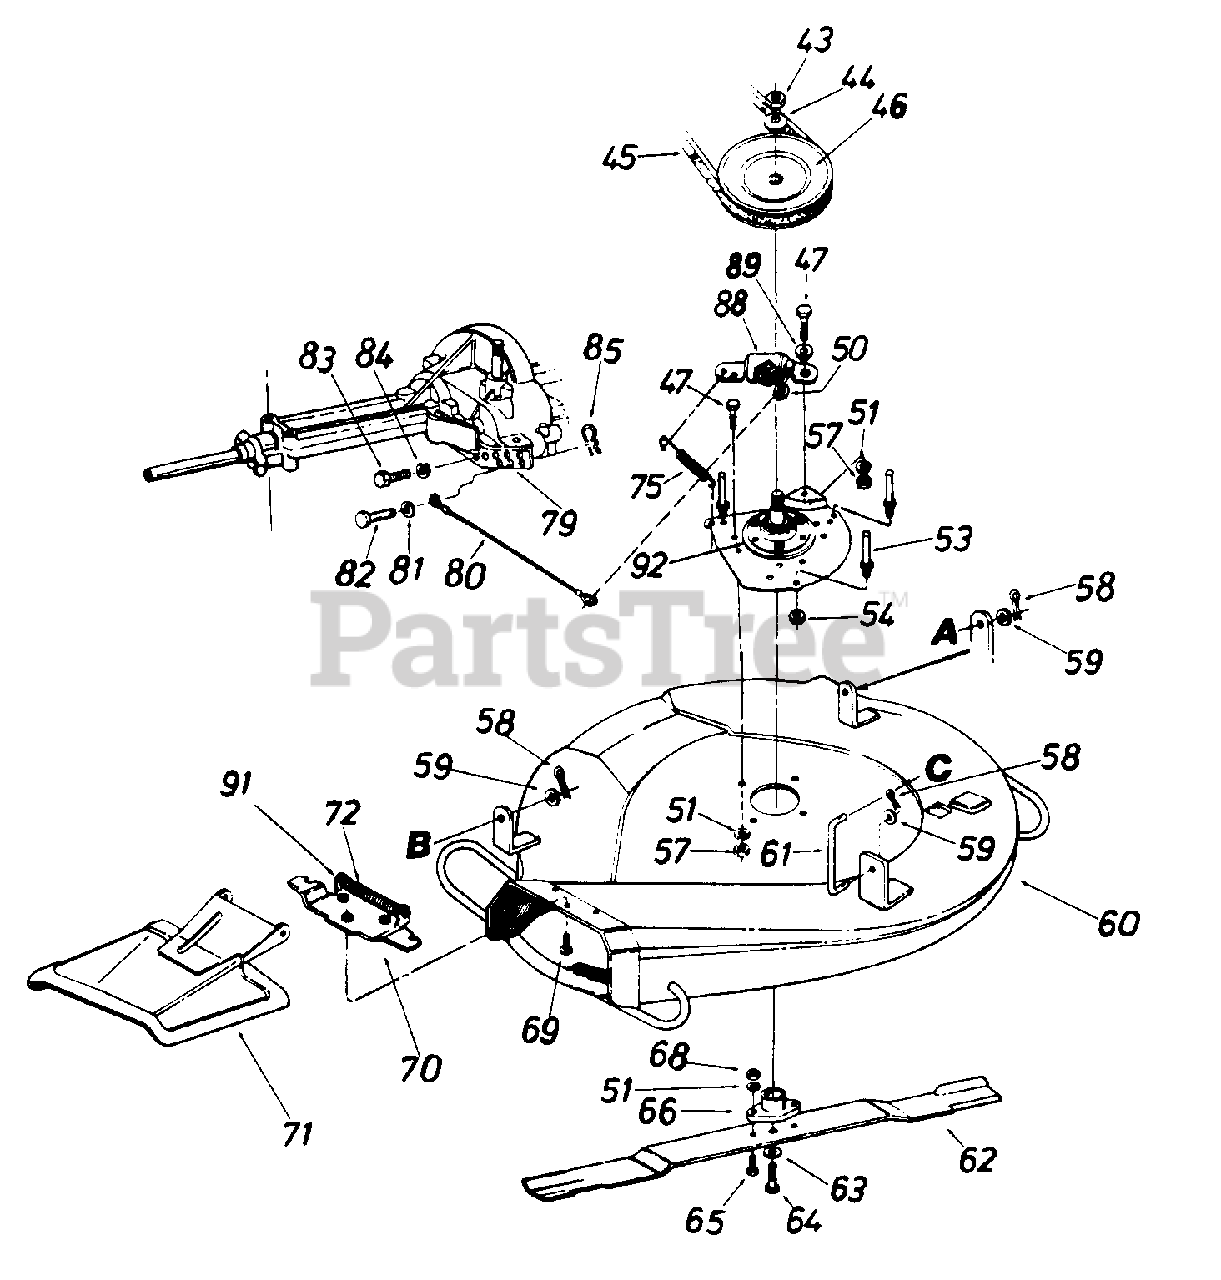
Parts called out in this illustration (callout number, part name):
43	Hex Jam Nut 5/8-18 Thd.
44	Bell-Wash. 63" I.D. x 1.25" O.D.
45	V-Belt 1/2 x 52" Lg.
46	1/2" V-Pulley .625" I.D. x 6.0" O.D.
47	Hex Bolt 5/16-18 x .75"
50	Cap Speed Nut 1/4" Rod
51	L-Wash. 5/16" I.D.
53	Stud 3/8-16 x 3.00" Lg.
54	Hex Jam Nut 3/8-16 Thd.
57	Hex Nut 5/16-18 Thd.
58	Intern. Cotter Pin 1/2 Dia.
59	Fl-Wash. 385n I.D. x 87"
60	26" Deck Ass'y.
61	Deck Link 3.9" Lg.
62	26n High Lift Blade
63	Bell-Wash. .39" I.D. x 1.38"
64	Hex Bolt 3/8-24 x 1.0"
65	Hex Bolt Spec. 5/16-24 x 1.0" Lg.
66	Blade Adapter
68	Hex Nut 5/16-24 Thd.
69	Hex Wash. S-Tap Scr. 1/4-20 x.50" Lg.
70	Adapter Plate-Chute
71	Chute Cover Ass'y. Comp.
72	Torsion Spring
75	Extension Spring 825" Lg.
79	Lower Inside Belt Guard
80	Brake Cable 11.75" Lg.
81	Fl-Wash. .281" I.D. x .50"
82	Clevis Pin 1/4" Dia. x .53" O.D.
83	Hex Bolt 1/4-20 x .62" Lg.
84	L-Wash. 1/4" I.D.
85	Intern. Cot.-Pin 5/16" Dia.
88	Blade Brake Brkt. Ass'y.
89	Shld. Spacer .27" Lg.
91	Hinge Pin
92	Blade Spindle Ass'y. Comp.
